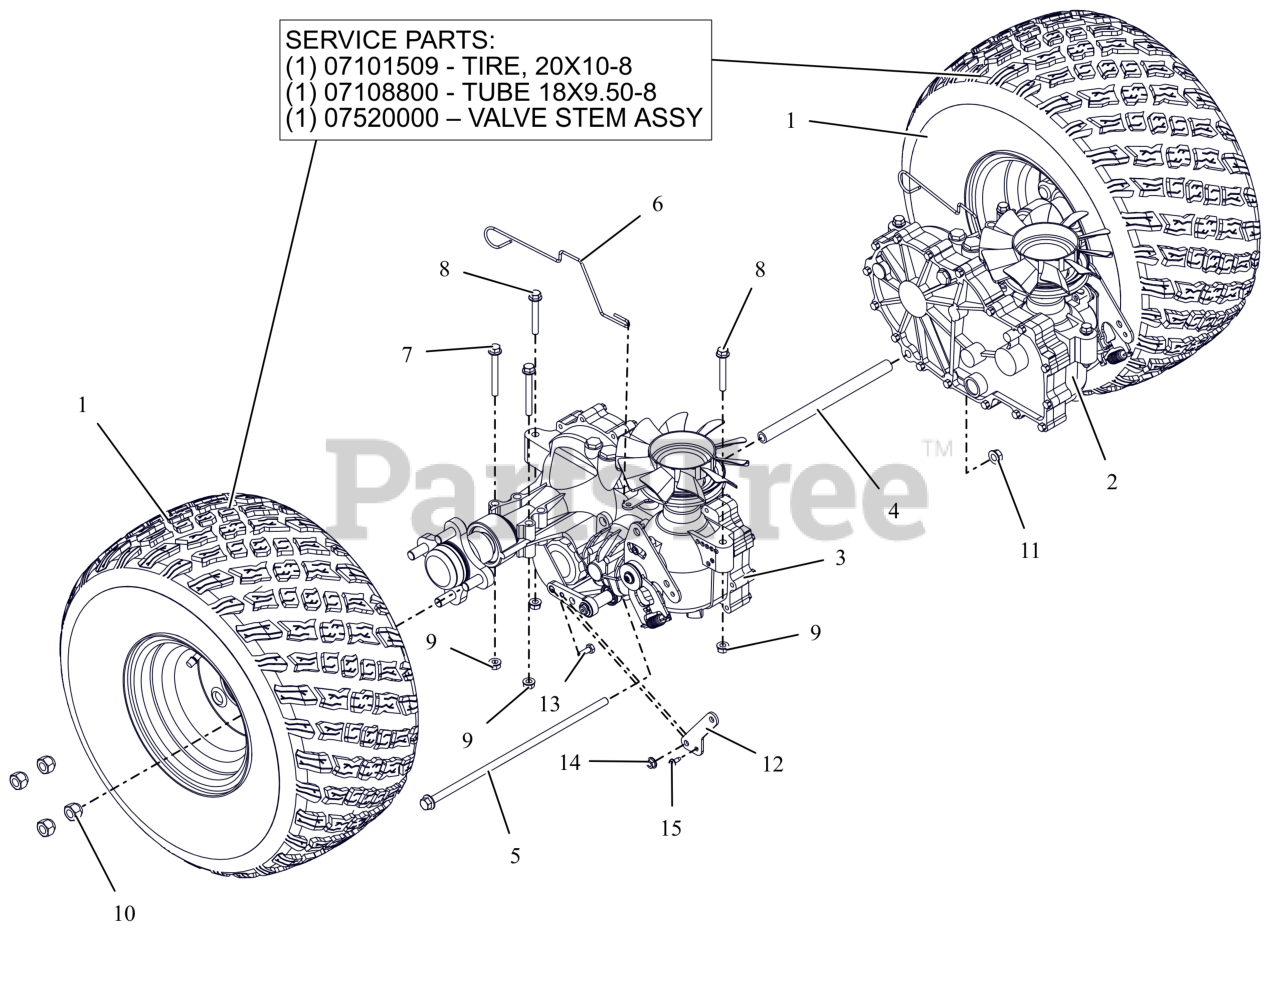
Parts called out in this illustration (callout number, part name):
1	ASM- TIRE/WHL 20X10-8
2	TRANSAXLE- 2800 - LH
3	TRANSAXLE- 2800 - RH
4	SPCR, TRANSAXLE .406 ID X .630 OD X 9.27 (BLACK)
5	BLT, HEX-FLG 0.375-16X13 GR5 ZC120
6	WIRE- DUMP VALVE LEVER
7	BLT,HEX-FLG .31-18X2.75 G5 ZCC
8	BLT,HEX-FLG .31-18X2.25 G5 ZCC
9	NUT,LK-CTR-FLG .31-18 GF ZCC
10	NUT, WHEEL .50-20 ZCC
11	NUT-LK-CTR-FLG .375-16 GF ZCC
12	PLATE- ADAPTOR PARKING BRAKE
13	BLT, HEX .25-20X.75 G5 ZCC
14	NUT-LK-CTR-FLG .25-20 ZC120
15	SCR,TAP #10-24X.50 HWH TR ZCC
